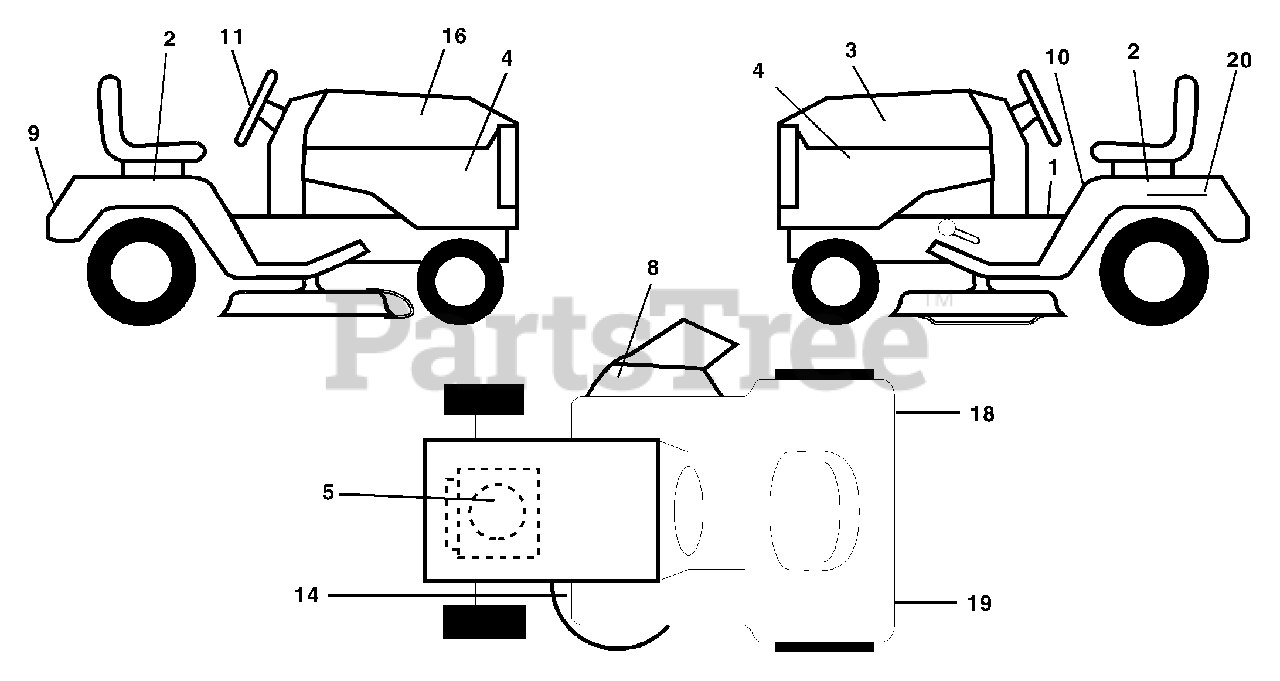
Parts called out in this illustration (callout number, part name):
2	Decal Fender Side
3	Decal Hood LH
4	Decal Side Panel Logo
5	Decal HP Engine
8	Decal Warning Mult-Language
9	Decal Fender Logo
10	Decal Fender Danger E/F
11	Decal Ins Strg Whl
14	Decal V-Belt Schematic
16	Decal Hood Rh
18	Decal Fender Reflector RH
19	Decal Fender Reflector LH
20	Decal Bat Dan/Psn
